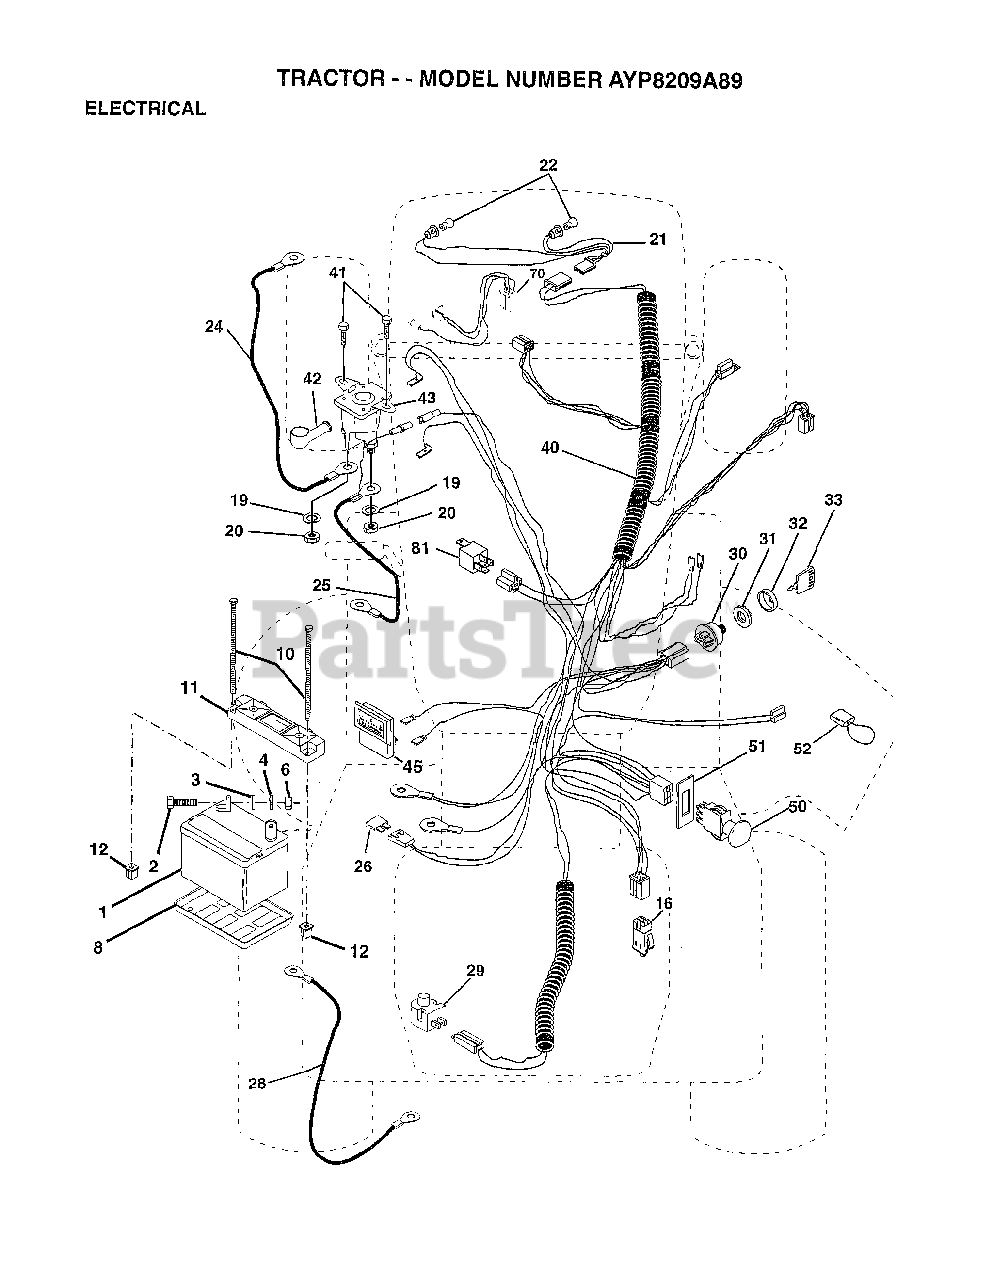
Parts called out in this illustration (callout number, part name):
3	WASHER
4	LOCKWASHER
8	"TRAY T, BATTERY"
11	HOLDDOWN BATTERY
16	SWITCH INTERLOCK
20	NUT
21	"HARNESS,LIGHT SOC"
22	HEADLAMP BULB
24	CABLE-BATTERY T
25	CABLE.6GA.12.5.
26	FUSE HYT
28	CABLE T
29	SWITCH.PLUNGER
30	SWITCH IGN 4POS
31	NUT IGNITION
32	COVER KEY SWITCH
33	KEY
40	HARNESS.IGNITON
41	SCREW
45	AMMETER
50	PTO SWITCH.BLK
51	RING RETAIN PTO
52	PROTECTION LOOP
70	HARNESS.ENG.B&S
81	RELAY ASSY T
